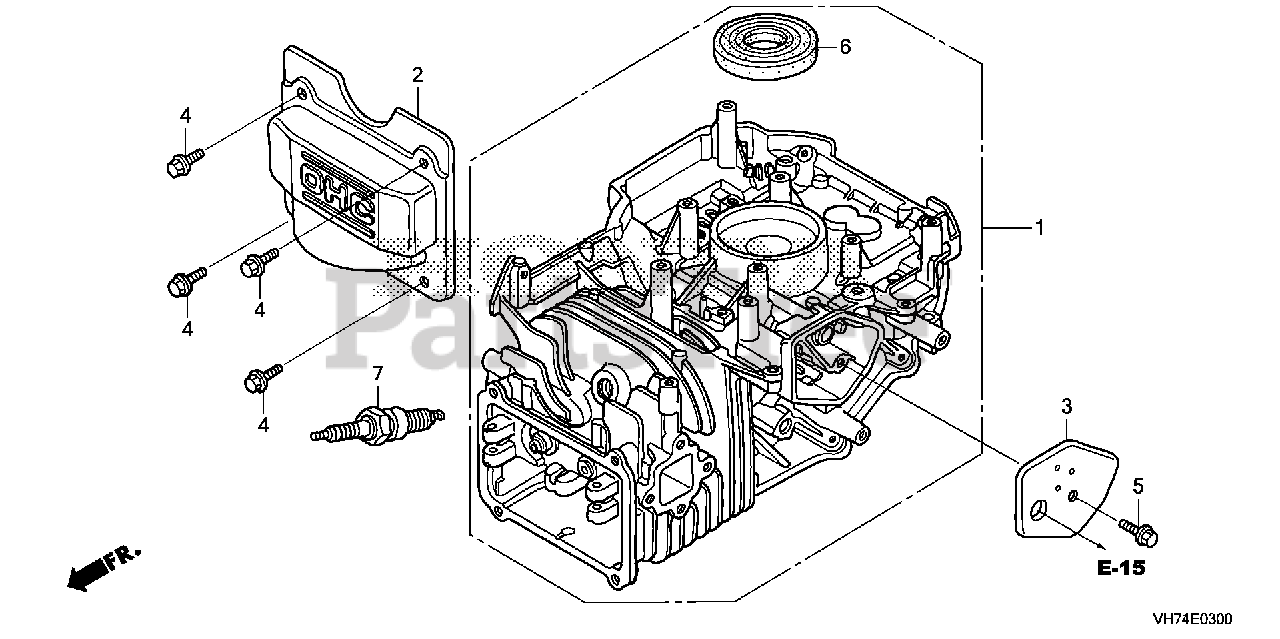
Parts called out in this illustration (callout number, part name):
1	CYLINDER ASSY.
1	BARREL ASSY,CYLN
2	COVER, HEAD
3	COVER, BREATHER (Honda Code 5580006). (BREATHER VALVE ASSY.)
4	BOLT, FLANGE (6X12) (CT200)
5	BOLT, FLANGE (6X14)
6	OIL SEAL (25.4X62X6)
7	SPARK PLUG (BPR5ES) (NGK)
